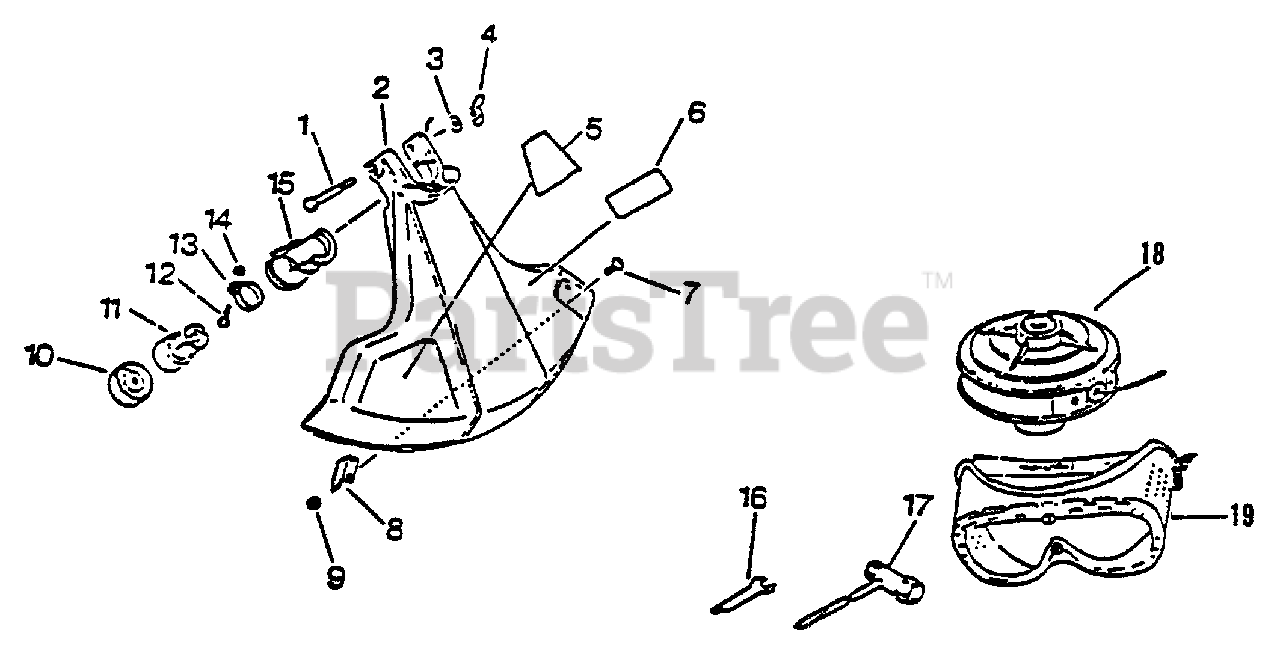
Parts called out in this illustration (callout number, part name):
1	BOLT - 6×50
2	DEBRIS SHIELD KIT
3	WASHER 6.5×11.5×0.8
4	NUT, WING 6
5	LABEL, CAUTION
6	LABEL, ECHO
7	SCREW 5×16
8	CUTTER, LINE
9	NUT M5
10	PLATE, ADAPTER - UPPER
11	GEAR CASE ASSY
12	BOLT M5×10
14	NUT M5
15	BRACKET, BEARING CASE
17	WRENCH
18	KNIFE, TRIMMER LINE
